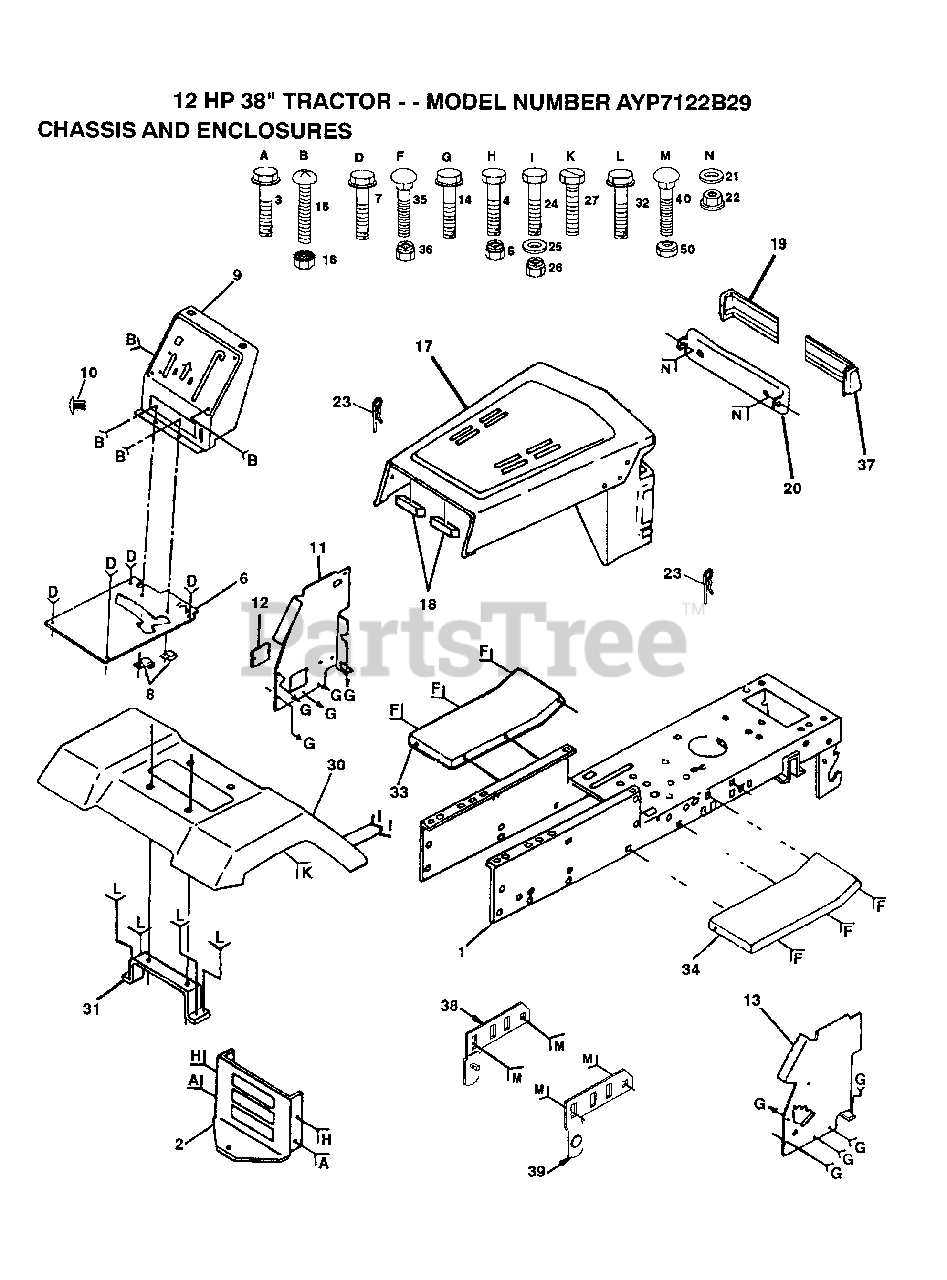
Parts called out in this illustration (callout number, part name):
2	DRAWBAR LT/YT
3	SCREW
7	SCREW LT
8	CLIP T
10	PLUG BUTTON T
11	PANEL DASH LH
12	COVER ACCESS
14	SCREW LT
15	SCREW
17	HOOD/GRILL ASM
21	WASHER PM
22	PAL NUT LT
23	SPRING.RETAINER
25	WASHER
27	SCREW LT
30	FENDER
32	SCREW
33	FOOTREST LH
34	FOOTREST RH
35	BOLT
38	BRKT ASM PIVOT LH
39	BRKT ASM PIVOT RH
40	BOLT
